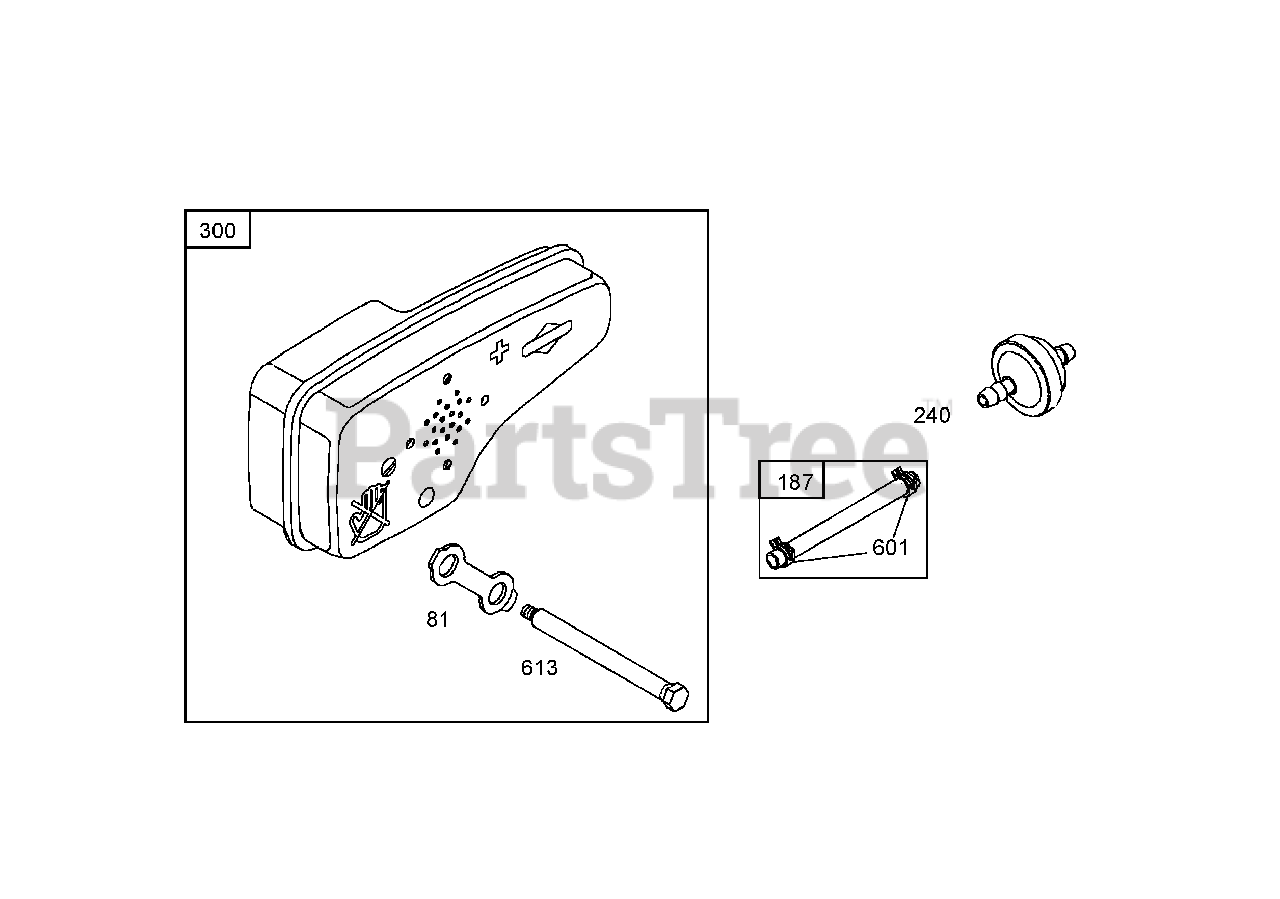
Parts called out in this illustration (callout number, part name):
81	Lock-Screw, Muffler
187	Line-Fuel (Cut to Required Length)
240	Filter
300	Muffler
601	Clamp-Hose
613	Screw
